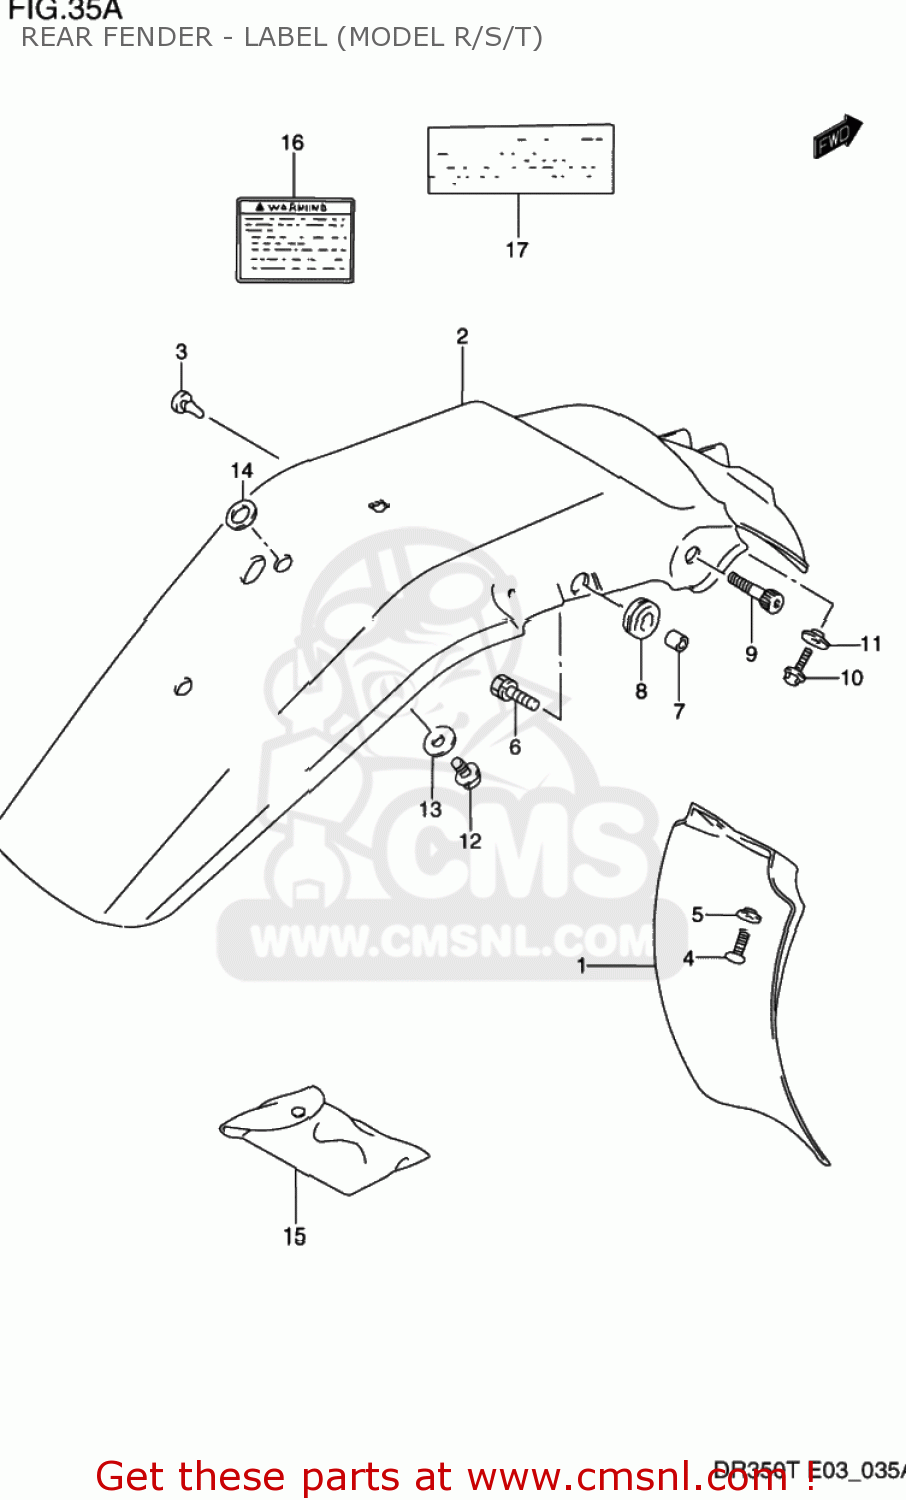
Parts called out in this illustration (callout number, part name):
1	BODY,RR FENDER FR
2	BODY,RR FENDER RR
3	CUSHION,RR FENDER SIDE
4	SCREW 6X12
5	WASHER
6	BOLT
7	SPACER (8.8X12X7)
8	CUSHION
9	BOLT(8X30)
10	BOLT
11	WASHER
12	BOLT, UPPER
13	WASHER
14	WASHER(14.2X26X1.2)
15	TOOL ASSY
16	LABEL
17	LABEL (MANUAL NOTICE)
